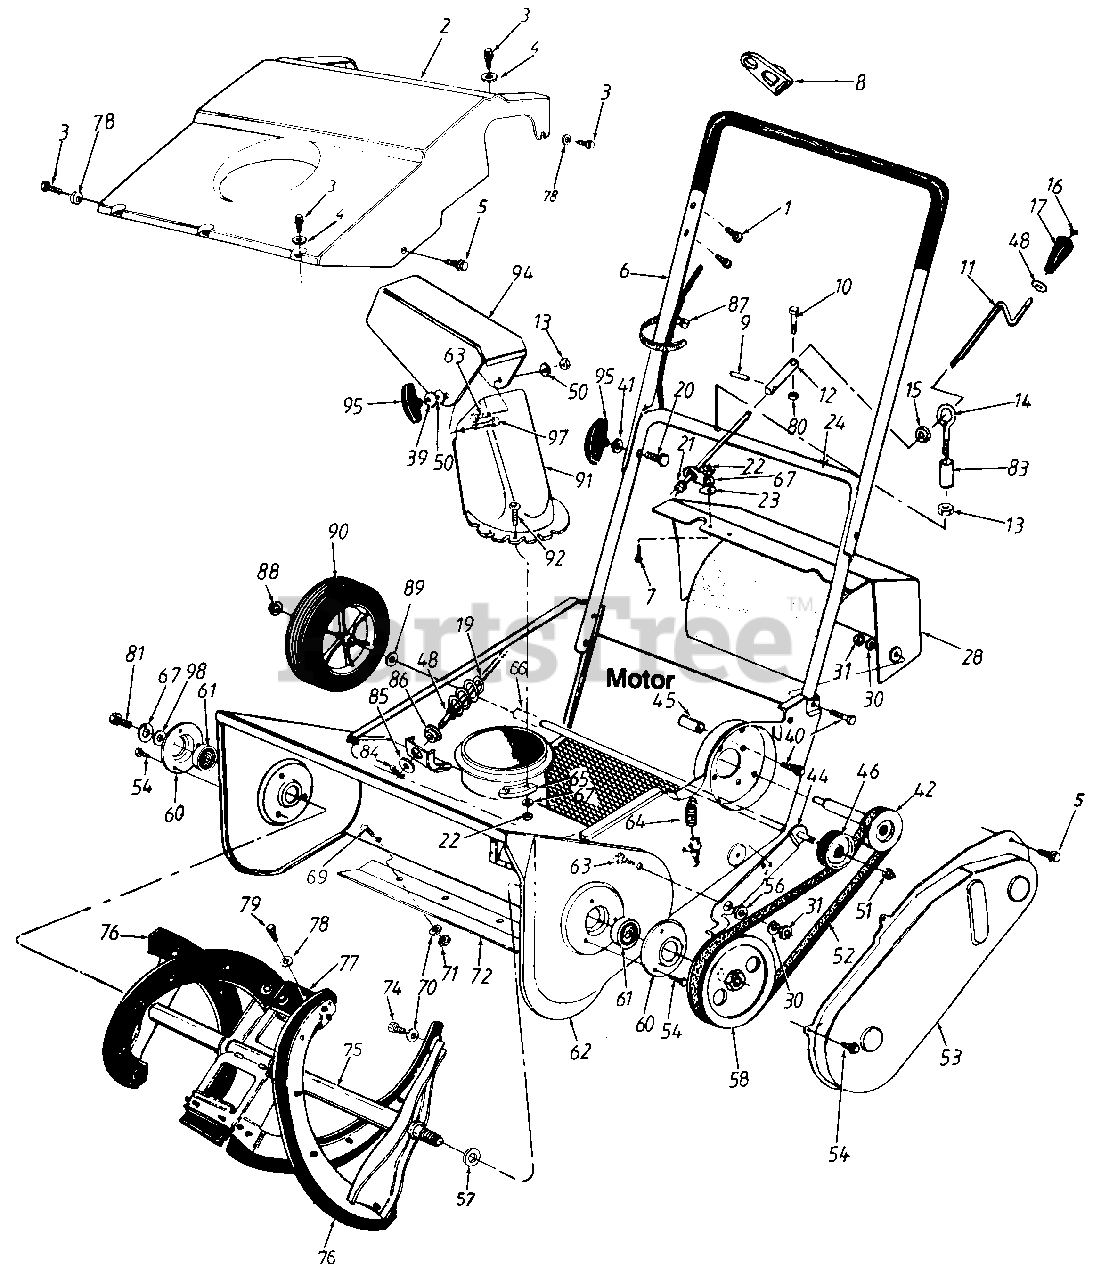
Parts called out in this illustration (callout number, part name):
1	Self-Tap Scr. #7 x 1" Lg.
2	Shroud-21" Snow Thrower
3	Tap Scr. #10 x 3/8"
4	Washer-Spring
5	Tap Scr. 1/4 x 5/8"
6	Upper Handle (Vinyl)
7	Hex Bolt 1/4-20 x 1/2"
8	Cord Minder
9	Roll Pin 1/8 x 5/8"
10	Mach. Scr. #6-32 x 3/4"
11	Chute Crank-Upper
12	Sleeve
13	Hex L-Nut 5/16-18 Thd.
14	Eyebolt
15	Grommet
16	Retainer-Push Cap 3/8"
17	Knob-Chute Rod
19	Chute Crank-Lower
20	Saddle Bolt 5/16-18 x 1-3/4"
21	Grommet
22	Hex Nut 1/4-20 Thd.
23	Chute Crank Brkt.
24	Lower Handle
28	Dash Panel
30	L-Wash. 5/16" I.D.
31	Hex Nut 5/16-18 Thd.
39	Bell-Wash. 345n I.D. x .88"
40	Hex Bolt 5/16-18 x 1-1/2"
41	Saddle Washer
42	Pulley and Shaft Assembly
44	Idler Arm Assembly
45	Spacer
46	Idler-Flat 2-1/8" O.D.
48	Washer 3/8" I.D. x 5/8" O.D.
50	Washer 5/16" I.D. x 1-1/4" O.D.
51	Hex L-Nut 3/8-24 Thd.
52	"V"-Belt
53	Belt Cover
54	Tap Scr. 1/4 x 3/8"
56	Spacer-Shoulder
57	Fl-Wash. .51n I.D.
58	"V"-Pulley 1/2-20 L.H. Thd.
62	Housing Assembly
63	Truss Mach. Scr. 5/16-18 x 3/4n
64	Spring-Idler
65	Keeper-Chute Flange
66	Axle-Wheel
67	L-Wash. 1/4n I.D.
69	Carriage Bolt 1/4-20 x .62n
70	Washer 1/4" I.D.
71	Hex Jam Nut 1/4-20 Thd.
72	Scraper Bar
74	Tap Scr. 1/4 x 5/8n
76	Rubber Spiral
77	Rubber Paddle
78	Washer 3/16" I.D. x 7/8" O.D.
79	Tap Scr. #10 x 5/8"
80	Hex L-Nut #6-32 Thd.
81	Tap Scr. 1/4 x 5/8"
83	Spacer-Eyebolt
84	Cotter Pin 3/32" x 3/4"
85	Washer 3/8" I.D. x 1-1/4" O.D.
86	Hex Bushing
87	Plastic Tie
88	Retainer-Push Cap 1/2"
89	Washer 1/2"
90	Wheel-7"
91	Lower Chute
92	Screw 1/4-20 x ln Truss Mach.
94	Upper Chute
95	Hand Knob
97	Carriage Bolt 5/16-18 x 1"
98	Fl-Wash. .25" I.D.
